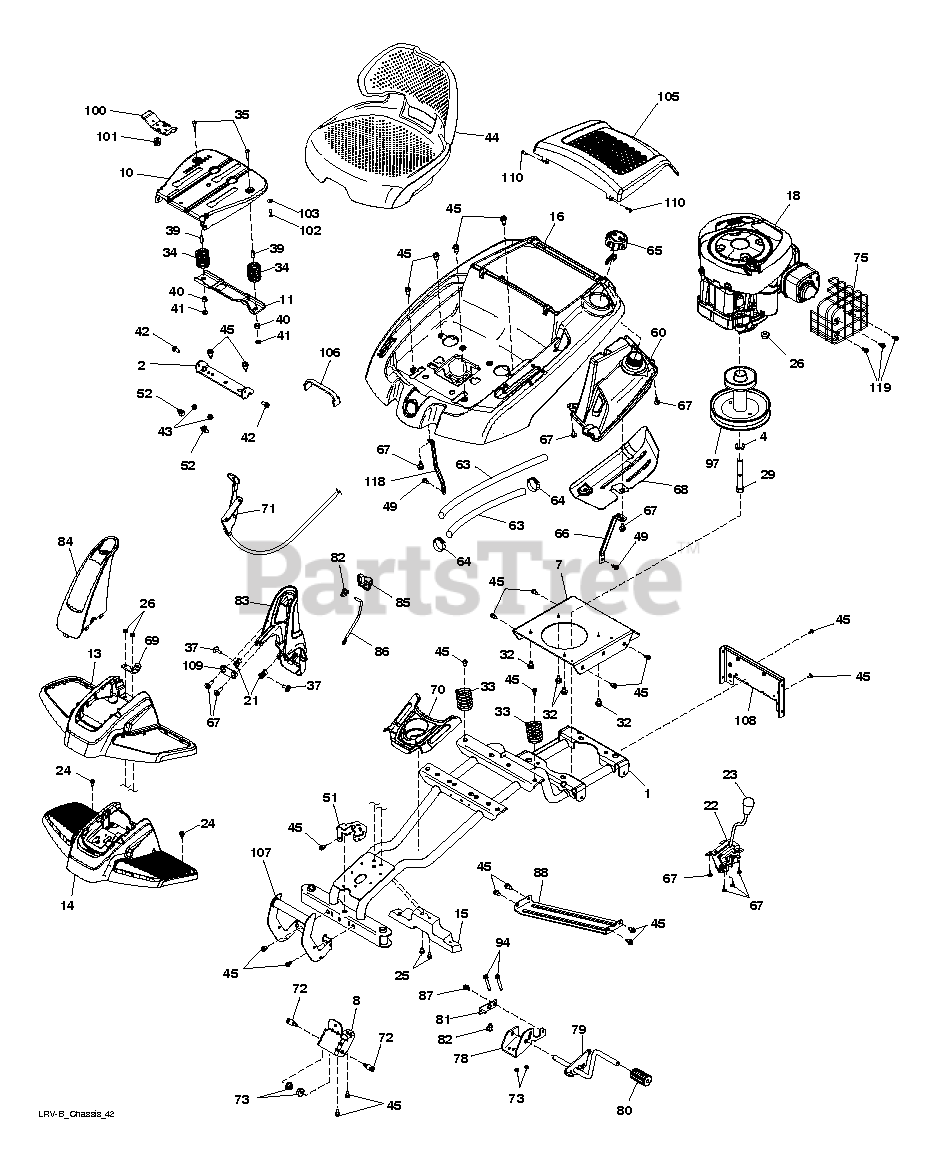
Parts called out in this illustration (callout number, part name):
2	BRKT.PIVOT.FENDER
4	LOCKWASHER
8	BRACKET.SUSP.CHAS.FR.LRV
10	PAN.ASM.SEAT.SHORT.SLD.ADJ.TEX
11	BRKT.MNT.OPC.SW.SEAT.
13	COVER.AESTH.FOOTREST.MS428
14	FOOTREST.STRUCTURAL.
15	SUPPORT. FOOTREST.LRV.MS428
16	PANEL CONTROL ASM.LRVB.GEARDRV
21	Speed Nut, U-Type
22	Clutch Deck Assembly, LRVB
23	KNOB.OVAL.CUSTOM.BLACK
24	SCREW.#10 X 0.750.BOS (2 2)
25	BOLT.CARRIAGE
26	NUT
29	Hex Bolt, 7/16-20 X 3.0 Gr5
32	SCREW.3/8-16
33	SPRING COMPRESSION
34	SPRING COMPRESSED
35	BOLT.ROUND.HEAD.SQUARE.NECK
37	SCREW.PAN.HEAD.#10
39	SPACER SPLIT 28X.96
41	NUT T
42	BOLT.SHOULDER.5/16-18
43	NUT.71038.31-18.HEX.NYLOCK
44	COMFORT.SEAT.ASSEMBLY
45	SCREW
49	SCREW 5/16-18X1
51	BRACKET, STEERING SUPPORT
52	PUSH CLIP
60	LRVB.FUEL.TANK.ASSEMBLY.EPA
63	RP PURGE LINE
64	HOSE CLAMP
65	CAP.FUEL.2 WAY VENT
67	SCREW.#10 X 0.500
70	CONSOLE.CENTER.CUPHOLDER
72	STUD.FASTNER.W/ANTI-ROTATE
73	NUT LOCK HEX FLANGE 5/16-18
75	GUARD.LRVB.MUFFLER
80	COVER.PEDAL.BRAKE.LRV
82	RETAINER CLIP
83	COLUMN.R.STEERING.ASM.ENG/SPAN
84	COLUMN.TOWER.FRONT.STEERINGLRV
87	BOLT.SHOULDER.5/16-18X
88	STRAP.CROSS.FRICTION.DRIVE
94	BOLT HEX FLGHD 5/16-18X3 GR. 5
97	PULLEY.ENGINE.LRVB.PMST
100	HANDLE.SLIDE.SEAT.TEX.BLACK
101	SPRING.LATCH.SEAT.TEX
103	WASHER 13/32 X 2-3/8 X 12GA
105	Engine Cover, Lrvb Pattern 2.X428
106	STRAP.BATTERY.LRVB
107	WELDMENT.FRT.PNT.BRUSHGAD.LR
119	SCREW NO 8-18 X 1/2;HEX WASHER
